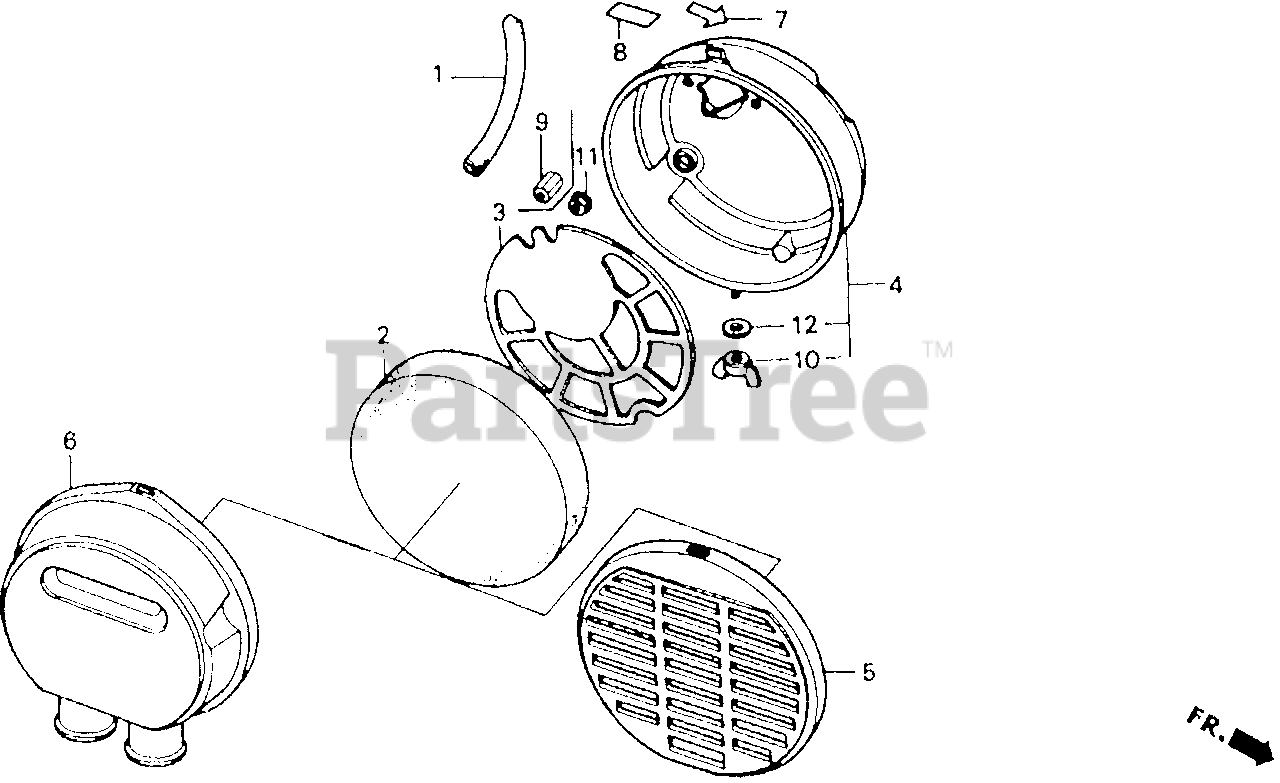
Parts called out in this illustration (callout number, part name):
1	TUBE, BREATHER
2	ELEMENT, AIR CLEANER
3	GRID, AIR CLEANER
4	HOUSING, AIR CLEANER
5	COVER, AIR CLEANER
6	COVER, AIR CLEANER
7	MARK, CHOKE
8	MARK, CHOKE
9	NUT (6X15)
10	WINGNUT, TOOL BOX SETTING
11	NUT, FLANGE (6MM)
12	WASHER, PLAIN (6MM)
